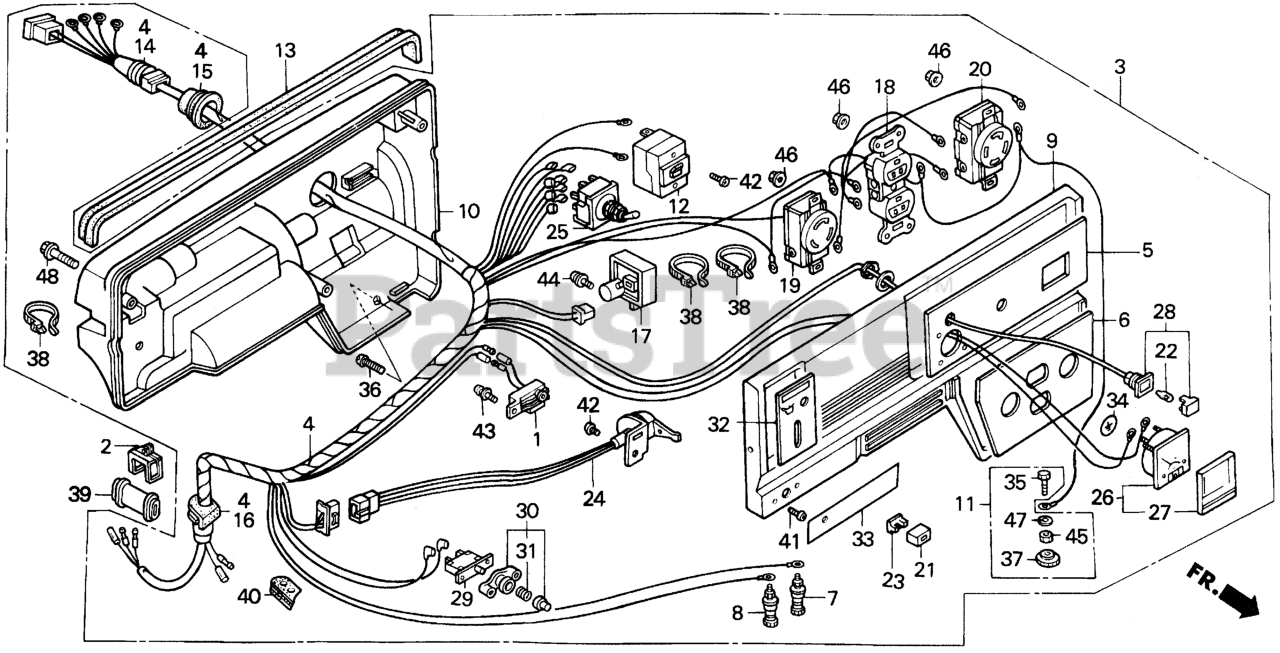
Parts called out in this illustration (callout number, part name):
1	ALERT UNIT, OIL
2	CLIP, WIRE
3	BOX ASSY., CONTROL *R8* (EM-A) (BRIGHT RED)
3	BOX ASSY., CONTROL *R8* (BRIGHT RED)
4	WIRE HARNESS ASSY. (EM-A)
5	MARK, SWITCH PANEL (EMS-A)
6	MARK, A.C. OUT (EMS-A) (NOT AVAILABLE)
6	MARK, A.C. OUT (EMS-A)
7	TERMINAL, D.C. OUT (+)
8	TERMINAL, D.C. OUTPUT (-)
9	PANEL, CONTROL *R8* (BRIGHT RED)
9	PANEL, CONTROL *R8* (BRIGHT RED) (NOT AVAILABLE)
10	CASE, CONTROL *R8* (BRIGHT RED)
11	TERMINAL SET, GROUND
12	BREAKER, CIRCUIT (19A)
13	RUBBER, CONTROL
14	GROMMET, A.C. WIRE
15	GROMMET, MAIN WIRE
16	GROMMET, SWITCH WIRE
17	DIODE ASSY.
18	RECEPTACLE (20A/125V) (MATSUSHITA)
19	RECEPTACLE (30A/125V)
19	RECEPTACLE (3-PRONG) (30A/125V)
20	RECEPTACLE (4-PRONG) (30A/125-250V)
20	RECEPTACLE (30A/125-250V)
21	KNOB, PETCOCK LEVER
22	BULB, WEDGE BASE (12V/2W) Use from Frame SN 1001725.
23	BUSH, CONTROL KNOB
24	SWITCH ASSY., ENGINE STOP
25	SWITCH ASSY., VOLT CHANGE
26	METER ASSY., VOLT (300V)
27	LENS, METER
28	SOCKET ASSY., LAMP (GREEN) Use from Frame SN 1001725.
29	PROTECTOR, CIRCUIT (D.C.)
30	LENS ASSY., PROTECTOR
31	SPRING, COIL
32	MARK, ENGINE SWITCH
33	MARK, D.C. OUT
34	MARK, GROUND
35	BOLT, HEX. (6X22)
36	SCREW, GLOVE BOX
37	NUT, SPECIAL (6MM)
38	TIE, CABLE (NATURAL 225X5.0)
39	TUBE, CORD
40	GROMMET, TUBE
41	SCREW, PAN (3X12)
42	SCREW, PAN (4X6)
43	SCREW-WASHER (4X10)
44	SCREW-WASHER (4X12) Use up to Engine SN 2056819.
45	NUT, HEX. (6MM)
46	NUT, FLANGE (4MM)
47	WASHER, SPRING (6MM)
48	BOLT, FLANGE (6X40)
